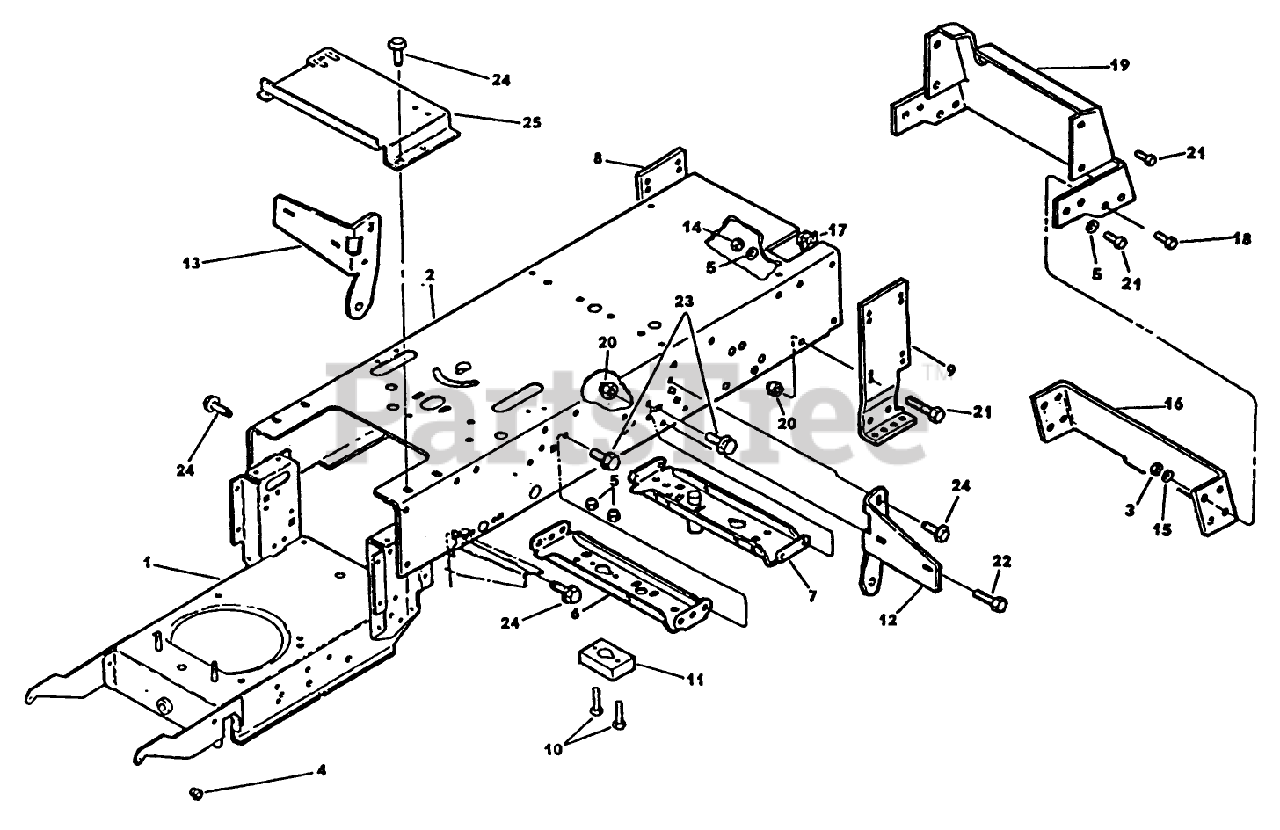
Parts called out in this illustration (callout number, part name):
3	NUT
4	BEARING-NYLINER
6	SUPPORT *B
10	SCREW
11	BRACKET-SUPPORT *B
13	SUPPORT - RH
14	NUT SS
15	WASHER
20	NUT
22	SCREW
25	SUPPORT, BATTERY *B
